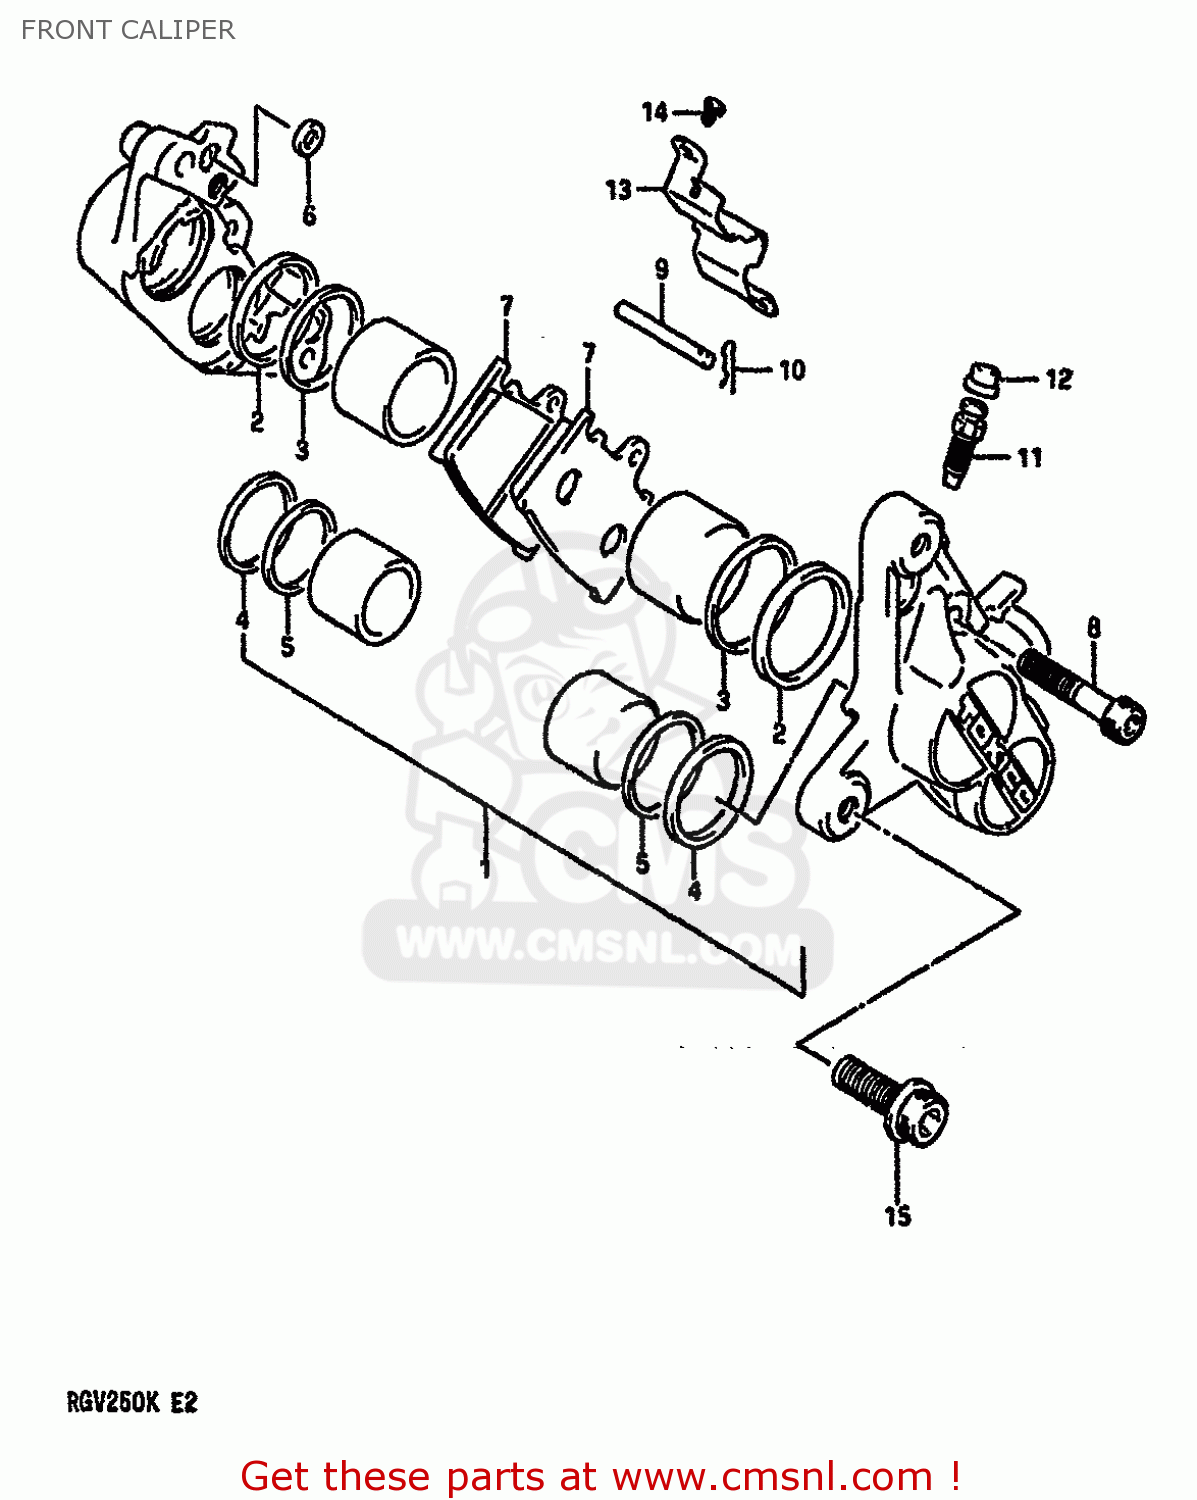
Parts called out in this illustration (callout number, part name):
1	PISTON SET
2	SEAL,PISTON
3	SEAL,WIPER
4	SEAL
5	SEAL,WIPER
6	SEAL,JOINT
7	PAD
8	BOLT,CALIPER
9	PIN,PAD
10	CLIP,PAD PIN
11	BLEEDER
12	CAP,BREATHER
13	COVER,R
14	SCREW,COVER
15	BOLT, FRAME JOINT
